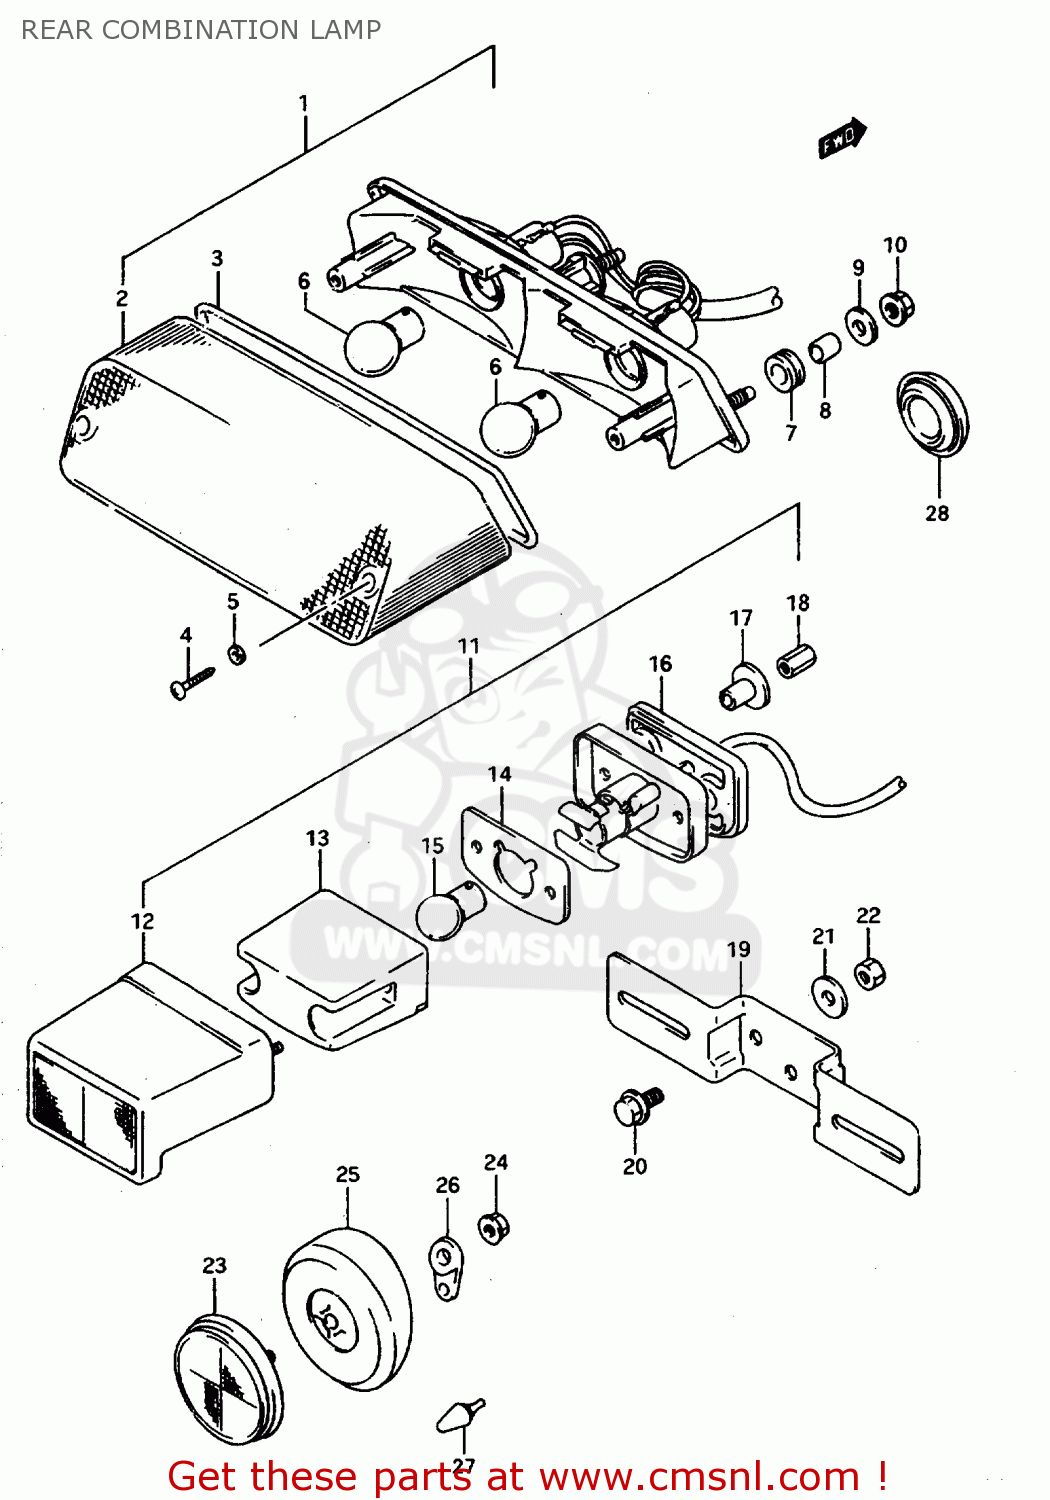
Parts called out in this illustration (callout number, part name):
1	LAMP ASSY,RR COMBINATION
2	LENS
3	GASKET (NAS)
4	SCREW
5	GASKET (NAS)
6	BULB(12V21/5W)
7	CUSHION
8	SPACER(6.1X8X9.5)
9	WASHER(6.5X18X1)
10	NUT
11	LAMP ASSY, LICENSE
12	COVER, LENS
13	LENS
14	GASKET,LICENSE LAMP (NAS)
15	BULB(12V5W,BF150-40160A)
16	CUSHION
17	SPACER
18	NUT
19	BRACKET,LICENSE PLATE
20	BOLT
21	WASHER(6.5X20X1.6)
22	NUT 6MM
23	REFLECTOR ASSY,RR
24	NUT
25	SPACER, REAR REFLECTOR
26	WASHER,RR REFLECTOR
27	CUSHION
28	CAP OD:40
